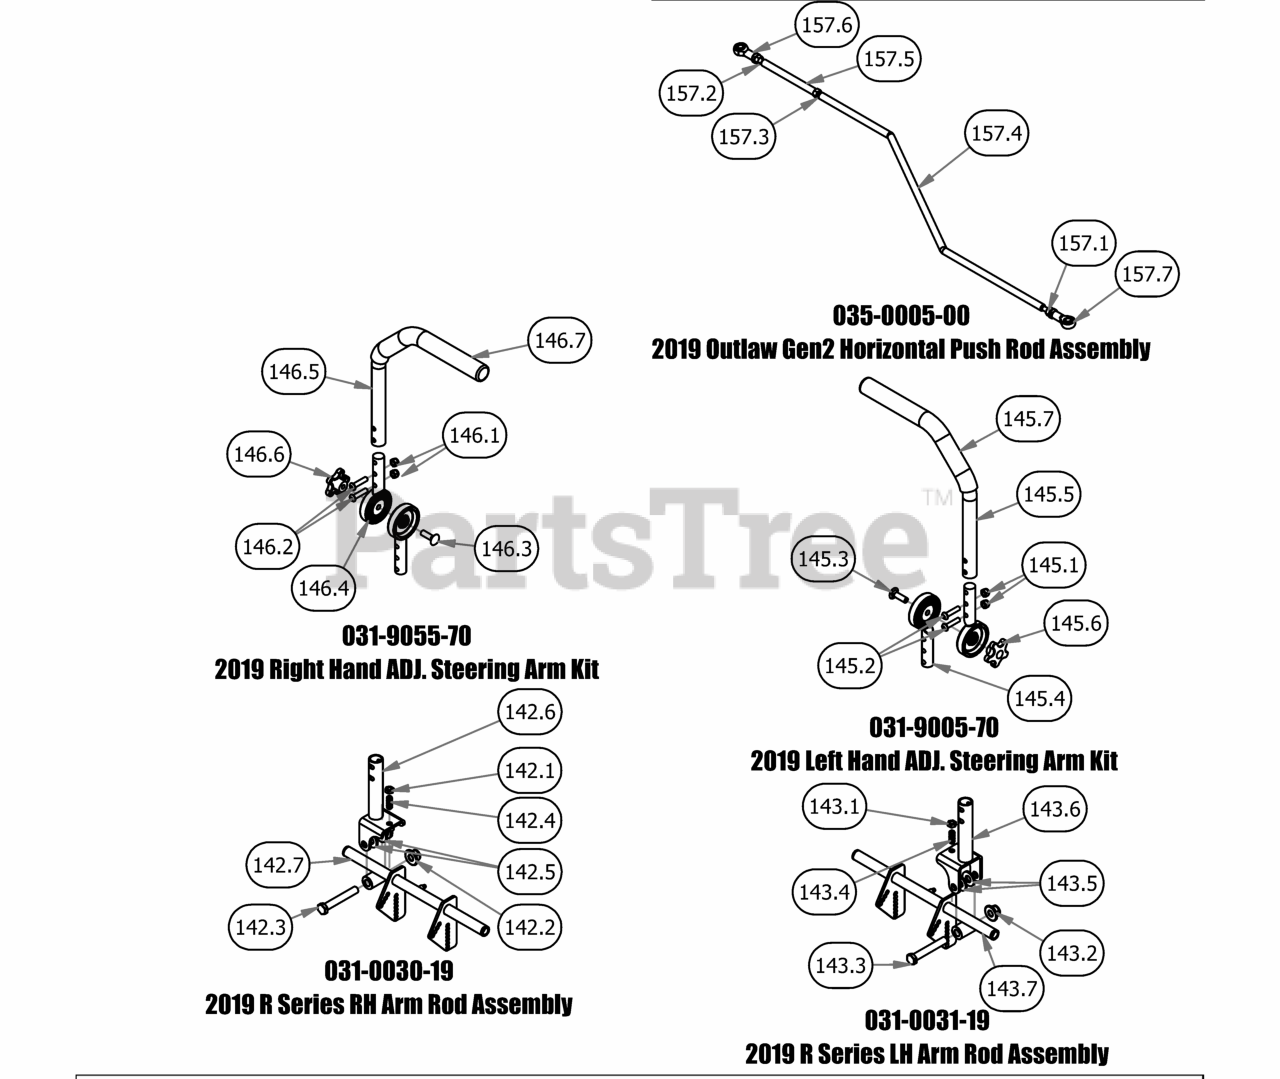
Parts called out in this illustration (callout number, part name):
142.1	3/8-16 Half Jam Nut
142.2	1/2-13 NYLON INSERT FLANGE LOCKNUT ZINC
142.3	1/2-13 x 3.25 GR 5 Hex Bolt Zinc
142.4	3/8-16 x 1 Set Socket Set Screw Cup Point
142.5	.505 Nylon Spacer
142.6	Drive Arm Pivot
142.7	2019 Drive Arm Actuator right
143.1	3/8-16 Half Jam Nut
143.2	1/2-13 NYLON INSERT FLANGE LOCKNUT ZINC
143.3	1/2-13 x 3.25 GR 5 Hex Bolt Zinc
143.4	3/8-16 x 1 Set Socket Set Screw Cup Point
143.5	.505 Nylon Spacer
143.6	Drive Arm Pivot
143.7	2019 Drive Arm Actuator left
145.1	5/16-18 Nylock Insert Locknut
145.2	5/16-18 UNC X 1-3/8" BHCS, TORX DRIVE, GR 5
145.3	3/8" x 1 1/4" Carriage Bolt
145.4	2019 Steering Arm Adjuster Casting
145.5	2019 Steering Arm Grip
145.6	Black Knob for Adjustable Steering Arm
145.7	Black Steering Arm Grip
146.1	5/16-18 Nylock Insert Locknut
146.2	5/16-18 UNC X 1-3/8" BHCS, TORX DRIVE, GR 5
146.3	3/8" x 1 1/4" Carriage Bolt
146.4	2019 Steering Arm Adjuster Casting
146.5	2019 Steering Arm Grip
146.6	Black Knob for Adjustable Steering Arm
146.7	Black Steering Arm Grip
157.1	5/16" RH Fine Threaded Jam Nut
157.2	5/16" LH Fine Threaded Jam Nut
157.3	3/8" Fine Threaded Jam Nut
157.4	2019 Outlaw Gen2 Horizontal Push Rod
157.5	2019 Outlaw Gen2 Horizontal Push Rod Adjuster
157.6	Spherical Rod End - Outlaw
157.7	Spherical Rod End - Outlaw
